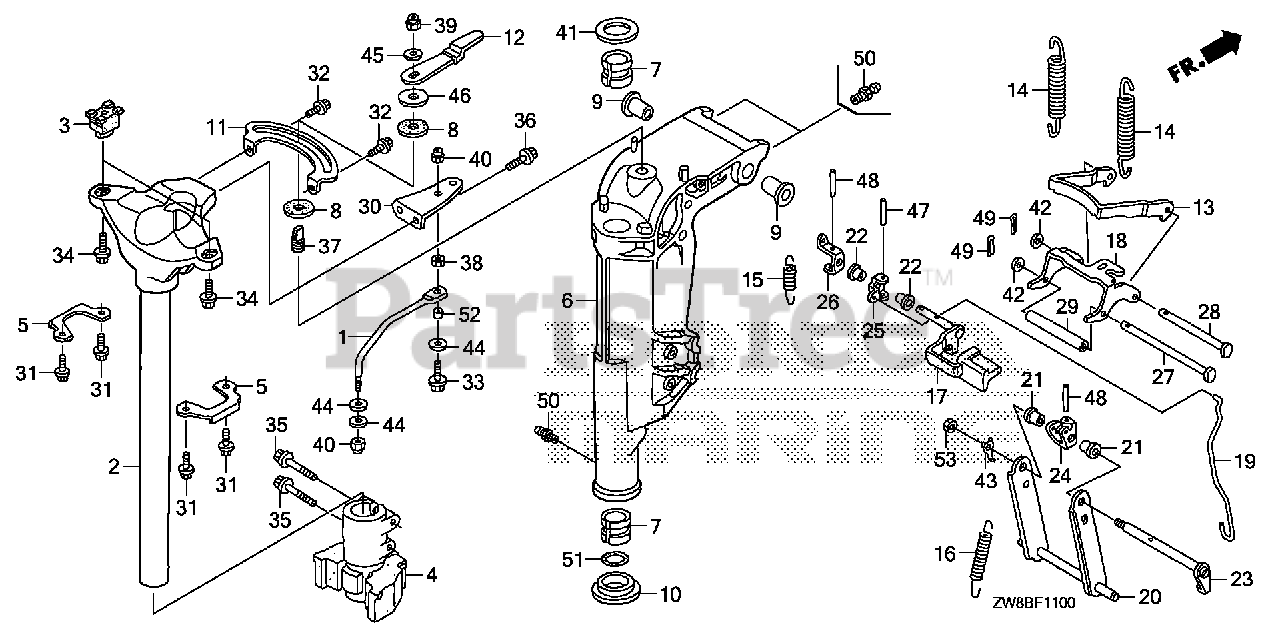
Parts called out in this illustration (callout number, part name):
1	ROD, STEERING
2	FRAME, MOUNTING (L)
3	RUBBER, MOUNTING (UPPER)
4	RUBBER, MOUNTING (LOWER)
5	COVER, MOUNTING RUBBER (UPPER)
6	CASE, SWIVEL *NH282MU* (L) (OYSTER SILVER METALLIC-U)
7	LINER, SWIVEL CASE
9	BUSH, SWIVEL CASE
10	COLLAR, SWIVEL CASE
13	HOOK, REVERSE LOCK
14	SPRING, REVERSE LOCK
15	SPRING, TILT LEVER
16	SPRING, TILT LINK
17	LEVER, TILT
18	ARM, REVERSE LOCK
19	ROD, RELEASE SWIVEL CASE
20	ARM, TILT
21	BUSH, TILT LEVER
22	BUSH, TILT LEVER
23	SHAFT, TILT
24	BRACKET, TILT SHAFT
25	BRACKET, RELEASE ROD
26	BRACKET, TILT LEVER
27	SHAFT, REVERSE LOCK (A)
28	SHAFT, REVERSE LOCK (B)
29	COLLAR, REVERSE LOCK
30	PLATE, STEERING
31	BOLT, FLANGE (6X12) Use from Frame SN 1005249.
33	BOLT (3/8-24 UNF)
34	BOLT, FLANGE (10X25)
35	BOLT, FLANGE (8X45)
36	BOLT, FLANGE (10X20)
38	NUT (3/8-24 UNF)
40	NUT, SELF-LOCK (3/8-24UNF)
41	WASHER, THRUST
42	WASHER, PLAIN (6MM) Use from Frame SN 4800713.
43	WASHER, LOCK
44	WASHER (10MM)
47	PIN, SPRING (3.0X22)
48	PIN, SPRING (3.0X25)
49	PIN, SPLIT (2.0)
50	NIPPLE, GREASE
51	O-RING (34X2.4)
52	COLLAR, STEERING ROD
53	NUT, HEX. (6MM)
